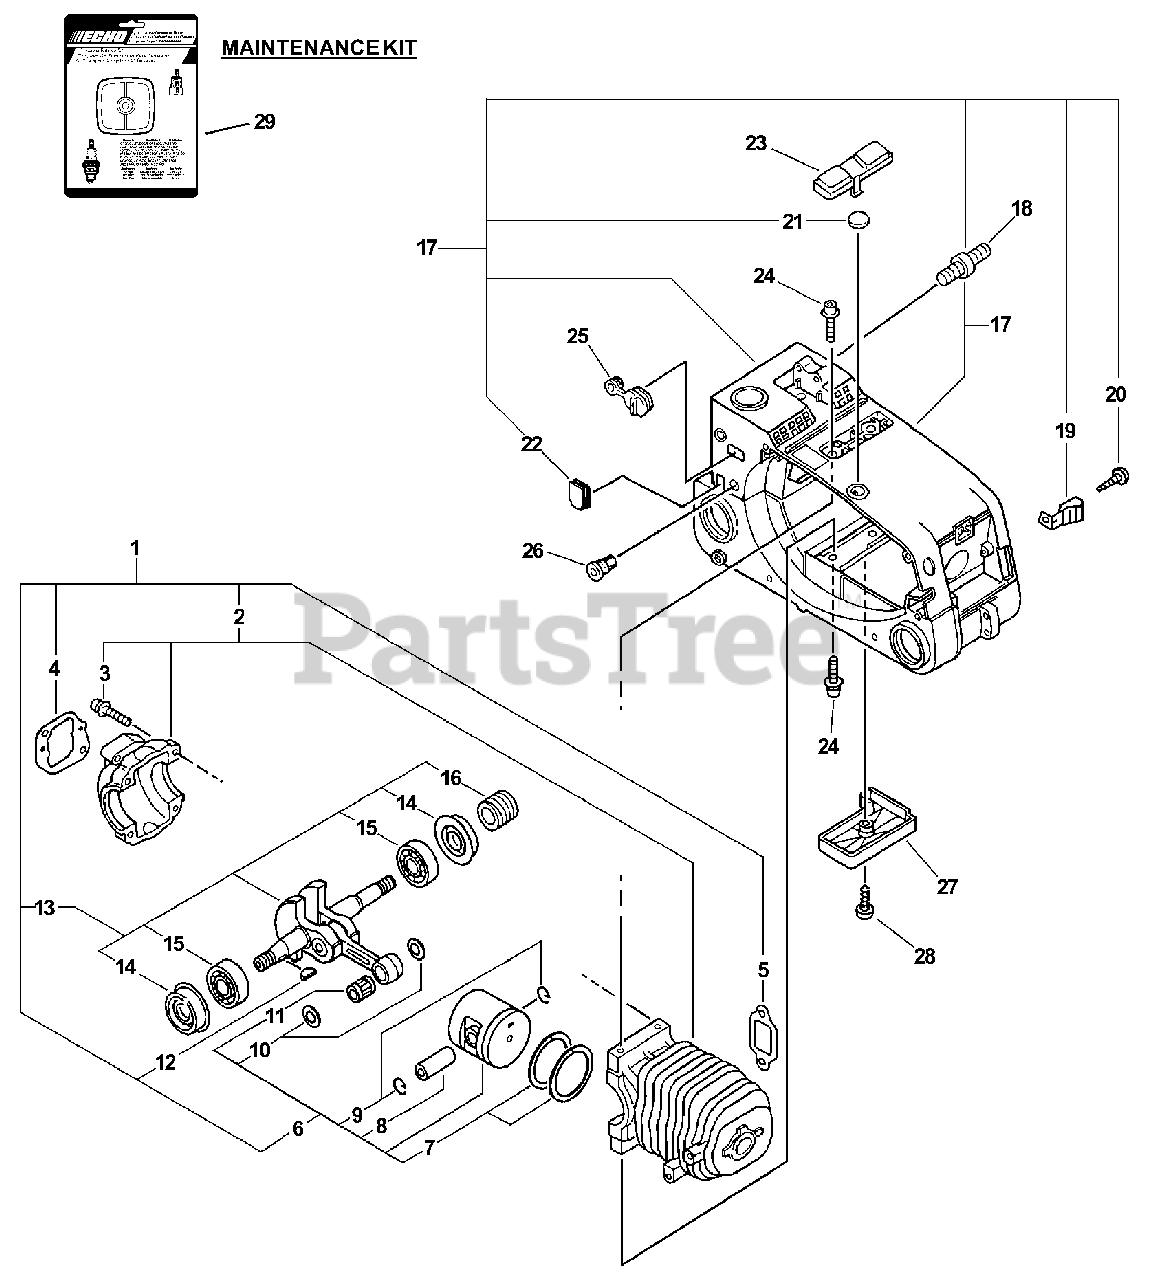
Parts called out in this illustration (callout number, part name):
1	SHORT BLOCK - SB1019
2	CRANKCASE SET
3	SCREW 5×25
4	GASKET, INTAKE
5	GASKET, MUFFLER
6	PISTON KIT
7	RING, PISTON
8	PIN, PISTON
9	RING, SNAP
10	WASHER, THRUST
11	BEARING, NEEDLE 8
12	KEY, WOODRUFF
13	CRANKSHAFT ASSY
14	SEAL, OIL
15	BEARING, BALL - 6201 C3
16	GEAR, WORM
17	ENGINE COVER KIT
18	BOLT, STUD 6
20	SCREW 4×10
24	BOLT 5×16
25	GROMMET
26	GROMMET, IDLE
28	SCREW 4×16
29	TUNE-UP KIT - REPOWER
